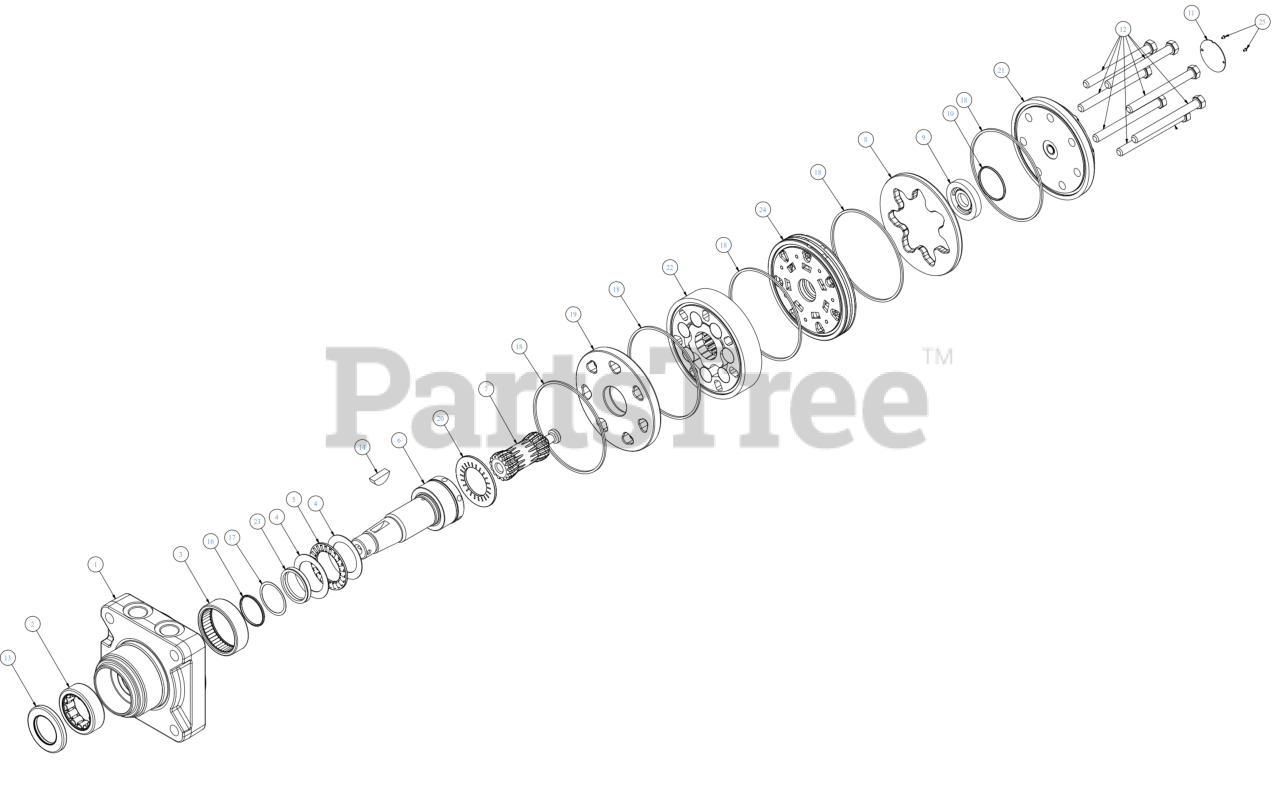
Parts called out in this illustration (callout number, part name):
1	HOUSING ASSEMBLY
4	WASHER, THRUST
5	THRUST BEARING
6	COUPLING SHAFT
8	COMMUTATOR RING
10	COMMUTATOR SEAL
11	IDENTIFICATION TAG
12	SPECIAL BOLT 3/8-24 UNF-A2
13	DIRT & WATER SEAL
14	WOODRUFF KEY
16	BACK-UP RING
17	BACK-UP WASHER
18	SEAL RING (FLUOROCARBON)
19	WEAR PLATE
20	THRUST BEARING
22	ROTOR ASSEMBLY
23	SHAFT SEAL
